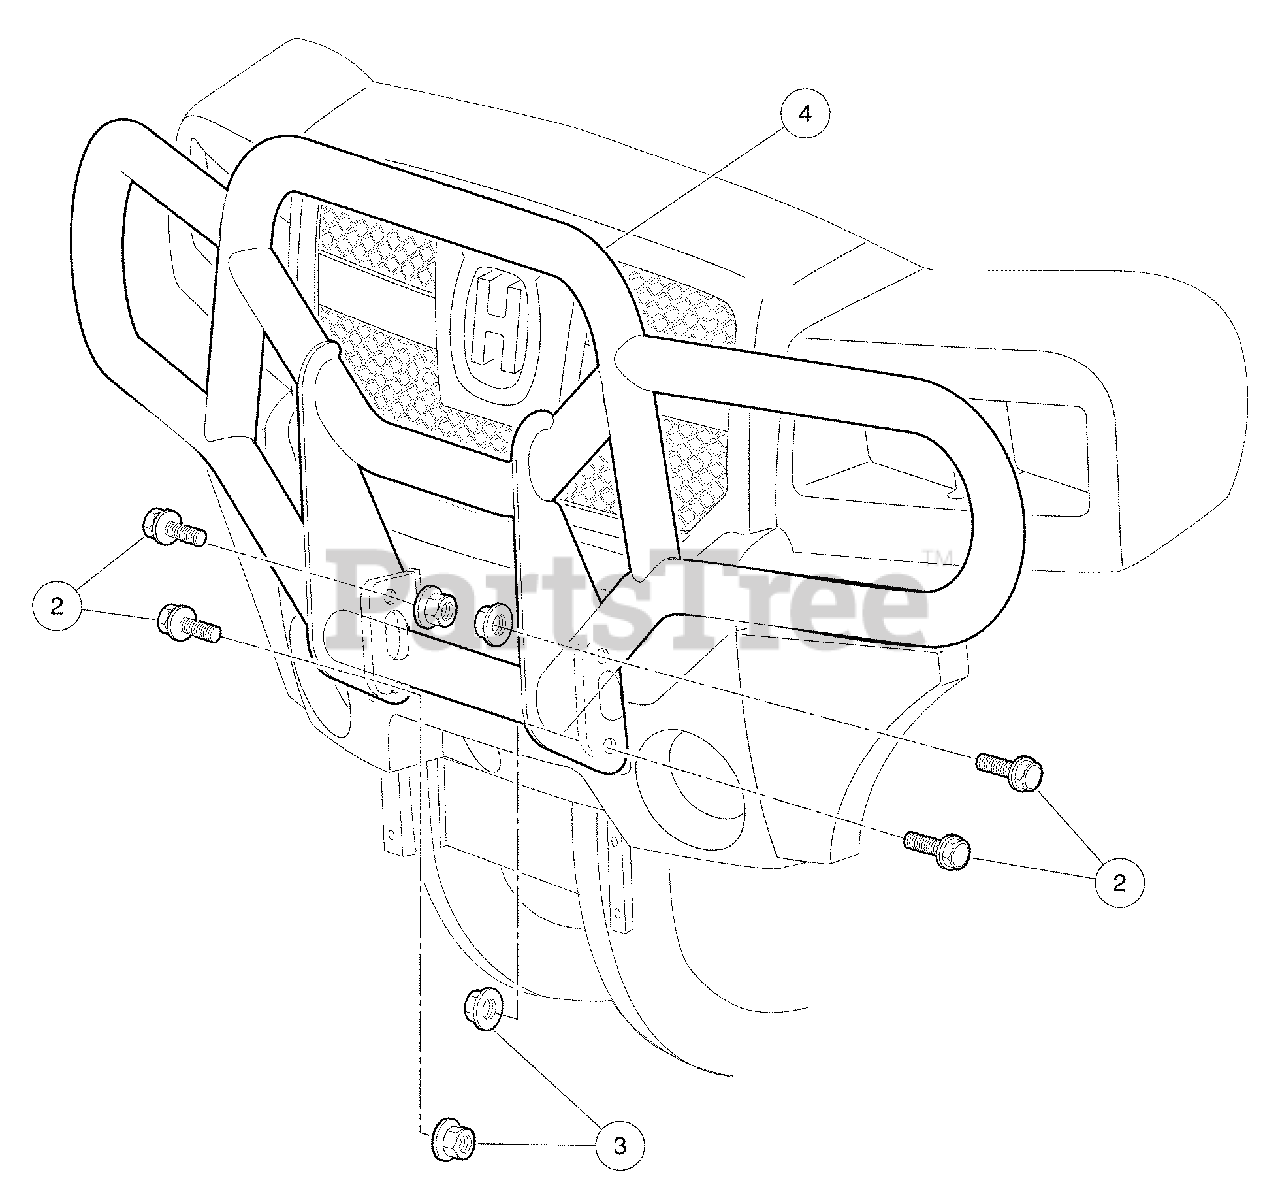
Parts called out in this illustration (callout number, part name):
1	Kit, Brush Guard Hus (includes items 2 through 4)
2	Screw, M10 X 1.25 X 30 Hex Blk
3	Nut, Flg, M10 X 1.25 Hex Blk
4	Weldment, Brushguard, HUV 4421
